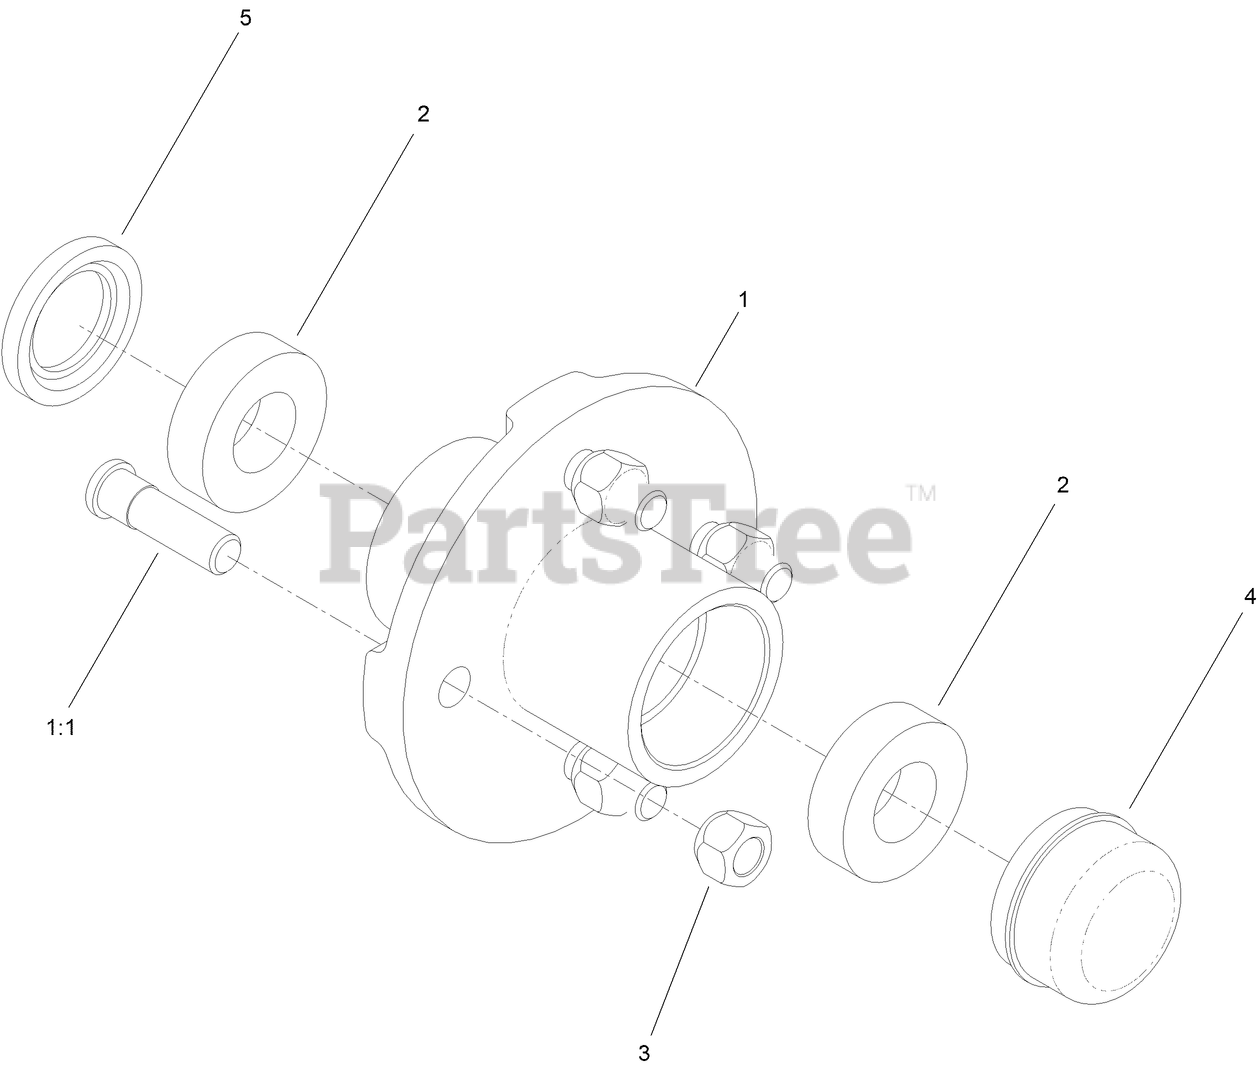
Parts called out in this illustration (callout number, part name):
1	HUB-4IN
1:1	STUD-WHEEL
2	BEARING-ROLLER
3	NUT-LUG
4	CAP-DUST
5	SEAL-HUB, WHEEL
